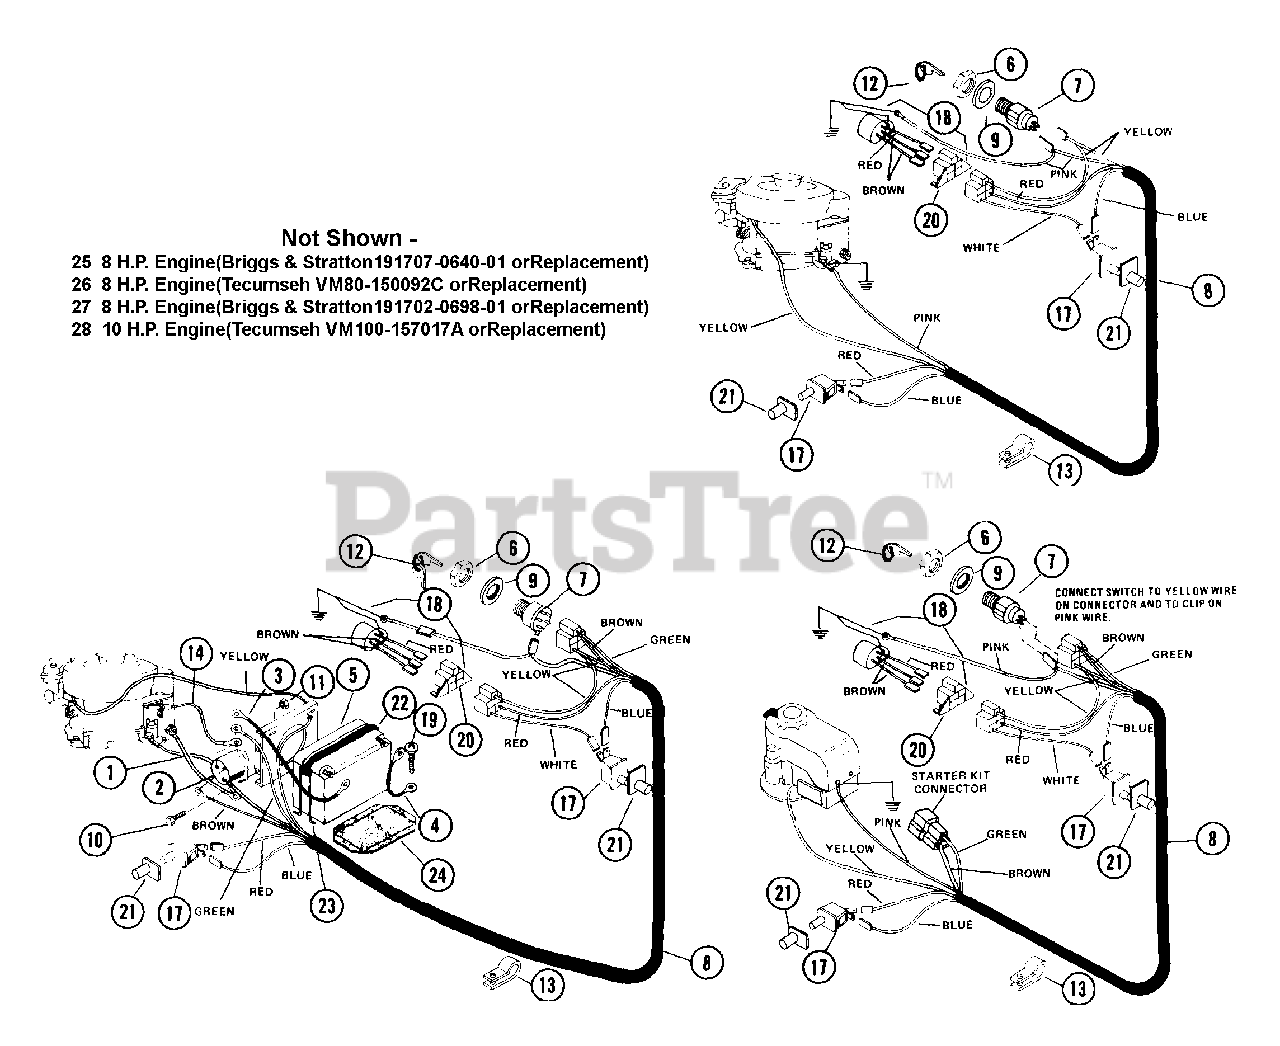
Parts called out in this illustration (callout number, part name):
1	GROUND CABLE .25X13.00X.31
2	SOLENOID,STARTER SWITCH
3	GROUND CABLE
4	GROUND WIRE
5	BATTERY
6	NUT .625-32 ALUM
7	IGNITION SWITCH ASSEMBLY
7	KEY SWITCH
8	WIRING HARNESS
8	WIRING HARNESS-B&S
9	WSHR-LK-INT .625X.045 PL
10	BLT-HEX .25-20X.50 PL GR2
11	NUT-LK-CTR .250-20 PL
12	KEYS
14	CHARGING WIRE
15	FUSE
18	MODULE T KIT
18	MODULE B KIT
19	SCR-TAP 10-24X.375 CRPH 1A
20	CONNECTOR
21	SCR-TAP 12-24X.50 HWH PL TR
22	BATTERY STRAP
23	HOOK
24	RUBBER PAD
25	8 H.P. Engine(Briggs & Stratton191707-0640-01 or Replacement)
26	8 H.P. Engine(Tecumseh VM80-150092C orReplacement)
27	8 H.P. Engine(Briggs & Stratton191702-0698-01 or Replacement)
28	10 H.P. Engine(Tecumseh VM100-157017A) orReplacement)
